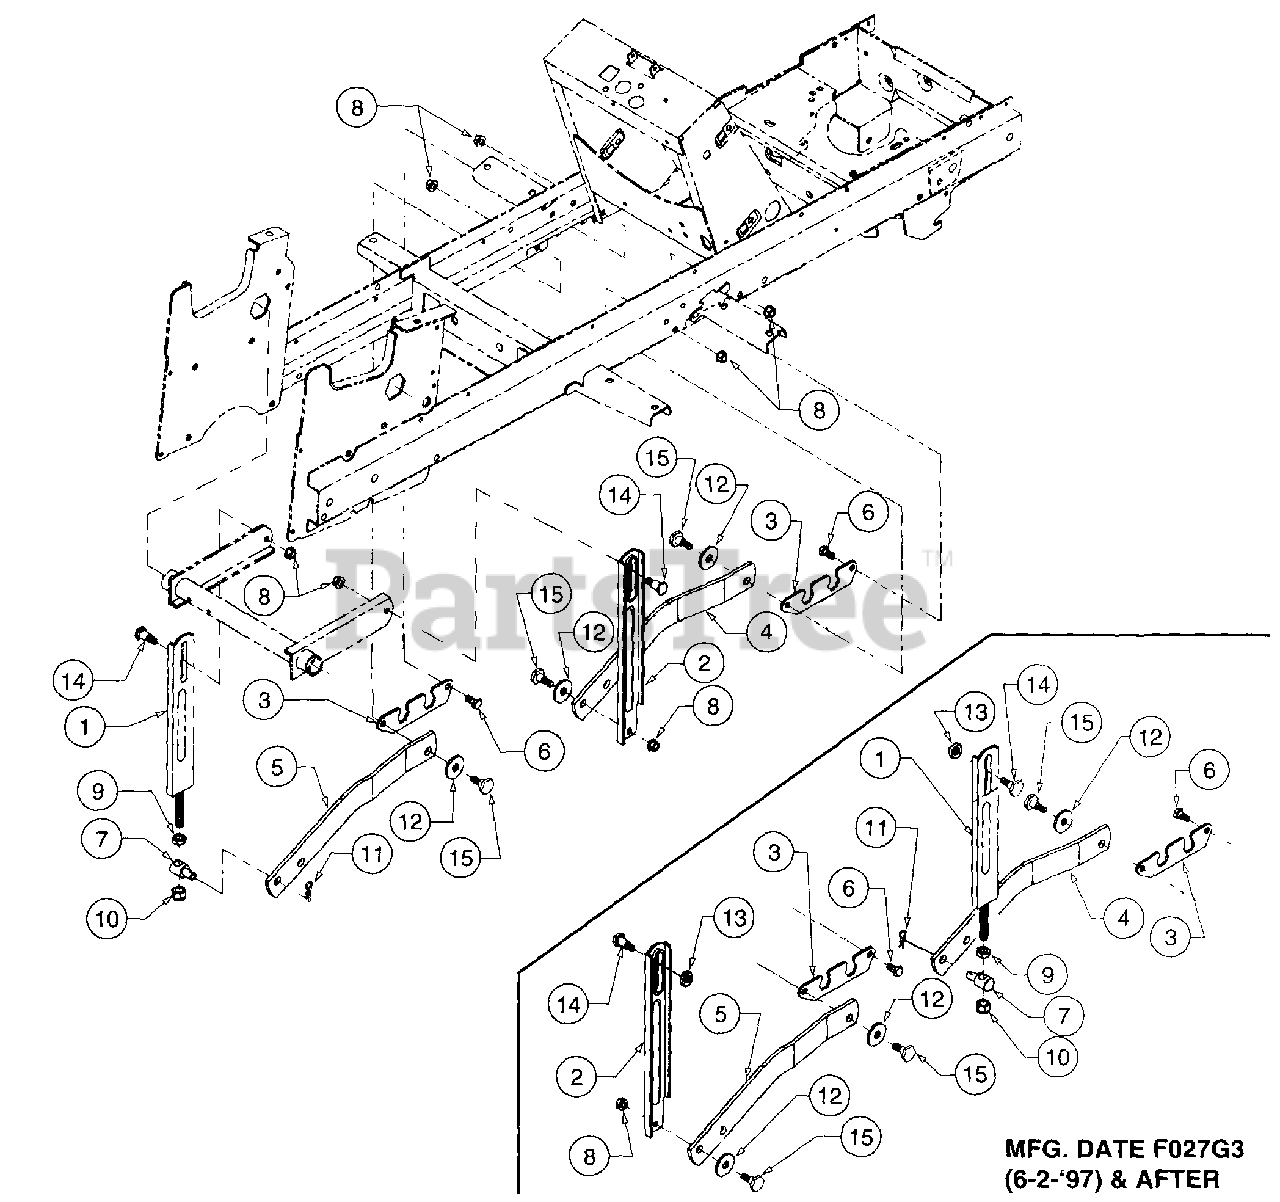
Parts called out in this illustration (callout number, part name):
7	Ferrule, Adjustment
8	Nut, Hex Flange Lock, 3/16
9	Nut, Hex Jam, 1/2-13 GR5
10	Nut, Hex Insert Lock, 1/2-13
11	Pin, Internal Cotter
12	Washer, Flat, .50 x 1.5 x .15
13	Washer, Flat, .531 x .875 x .15
14	Bolt, Shoulder
15	Bolt, Shoulder
